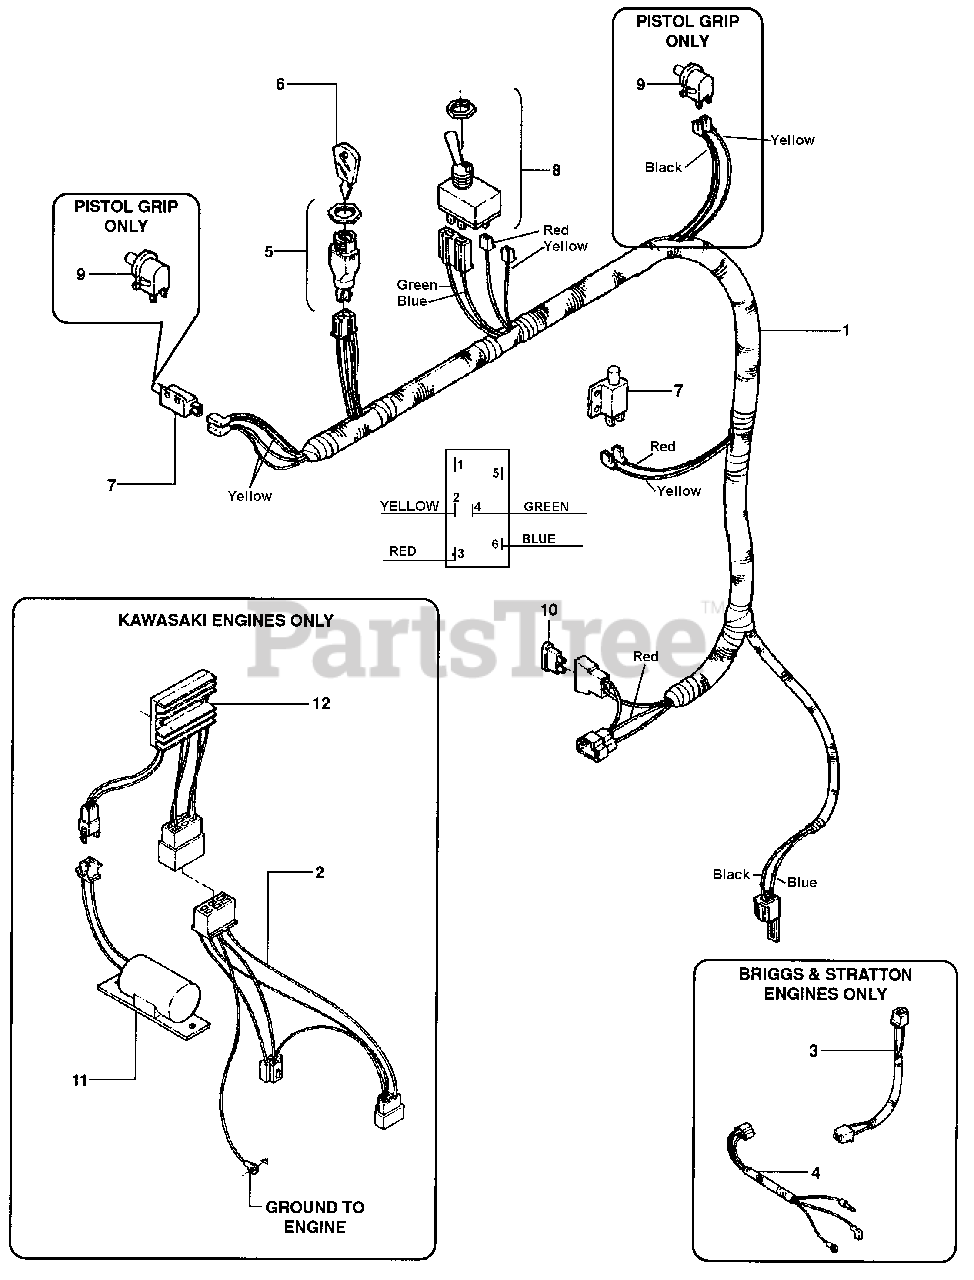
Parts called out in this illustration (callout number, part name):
1	HARNESS, Main Wire (Pistol Grip)
2	PIGTAIL, Engine (Kawasaki)
3	PIGTAIL, Clutch (Briggs & Stratton Only
4	PIGTAIL, Engine (Briggs & Stratton Only)
5	KEYSWITCH
6	KEY, Switch (With Cover)
7	SWITCH, OPC & Neutral NC
8	SWITCH, Blade Control
9	SWITCH, OPC (Pistol Grip) NC
11	CAPACITOR
12	MODULE (Kawasaki)
